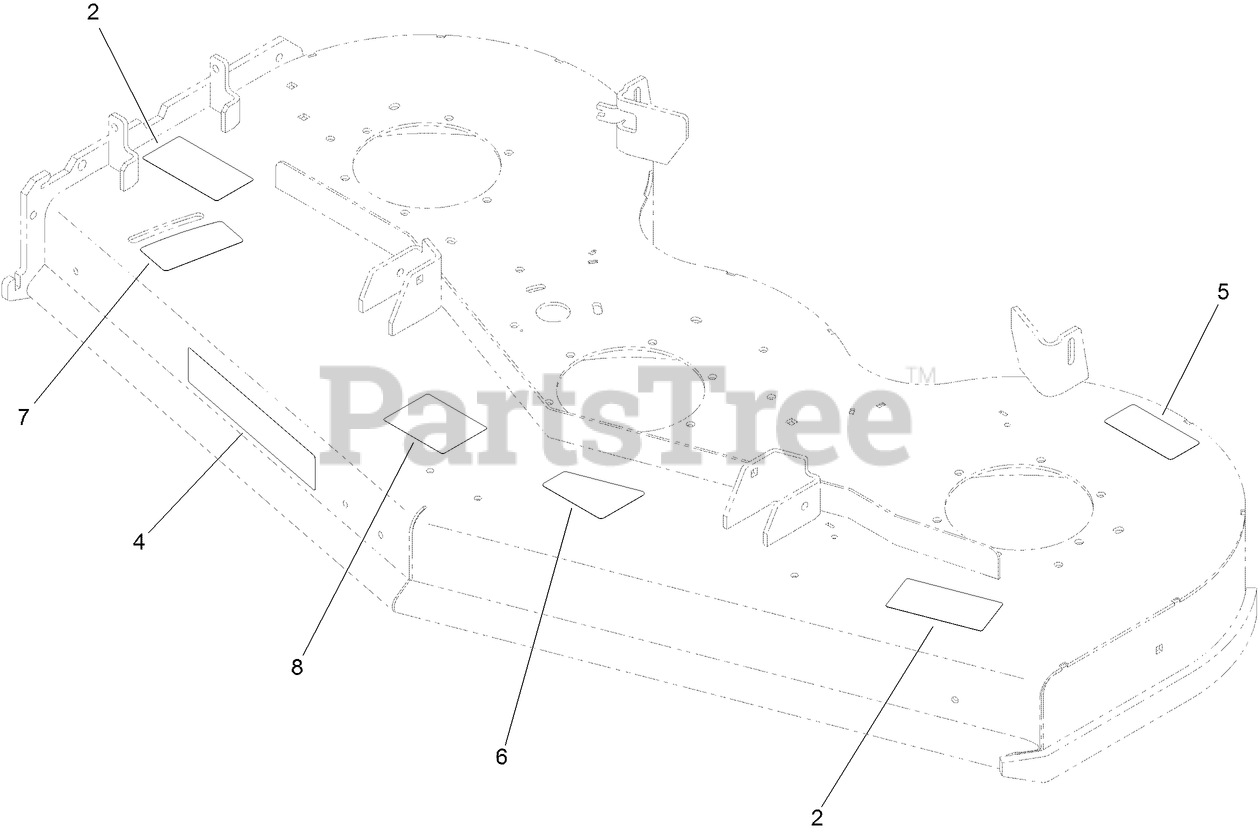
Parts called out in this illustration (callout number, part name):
2	DECAL-DANGER
5	DECAL-TORQUE, BLADE BOLT
6	DECAL-BELT, TENSION (CE)
7	DECAL-ADJUSTMENT, BAFFLE
8	DECAL-SCALP, ANTI
